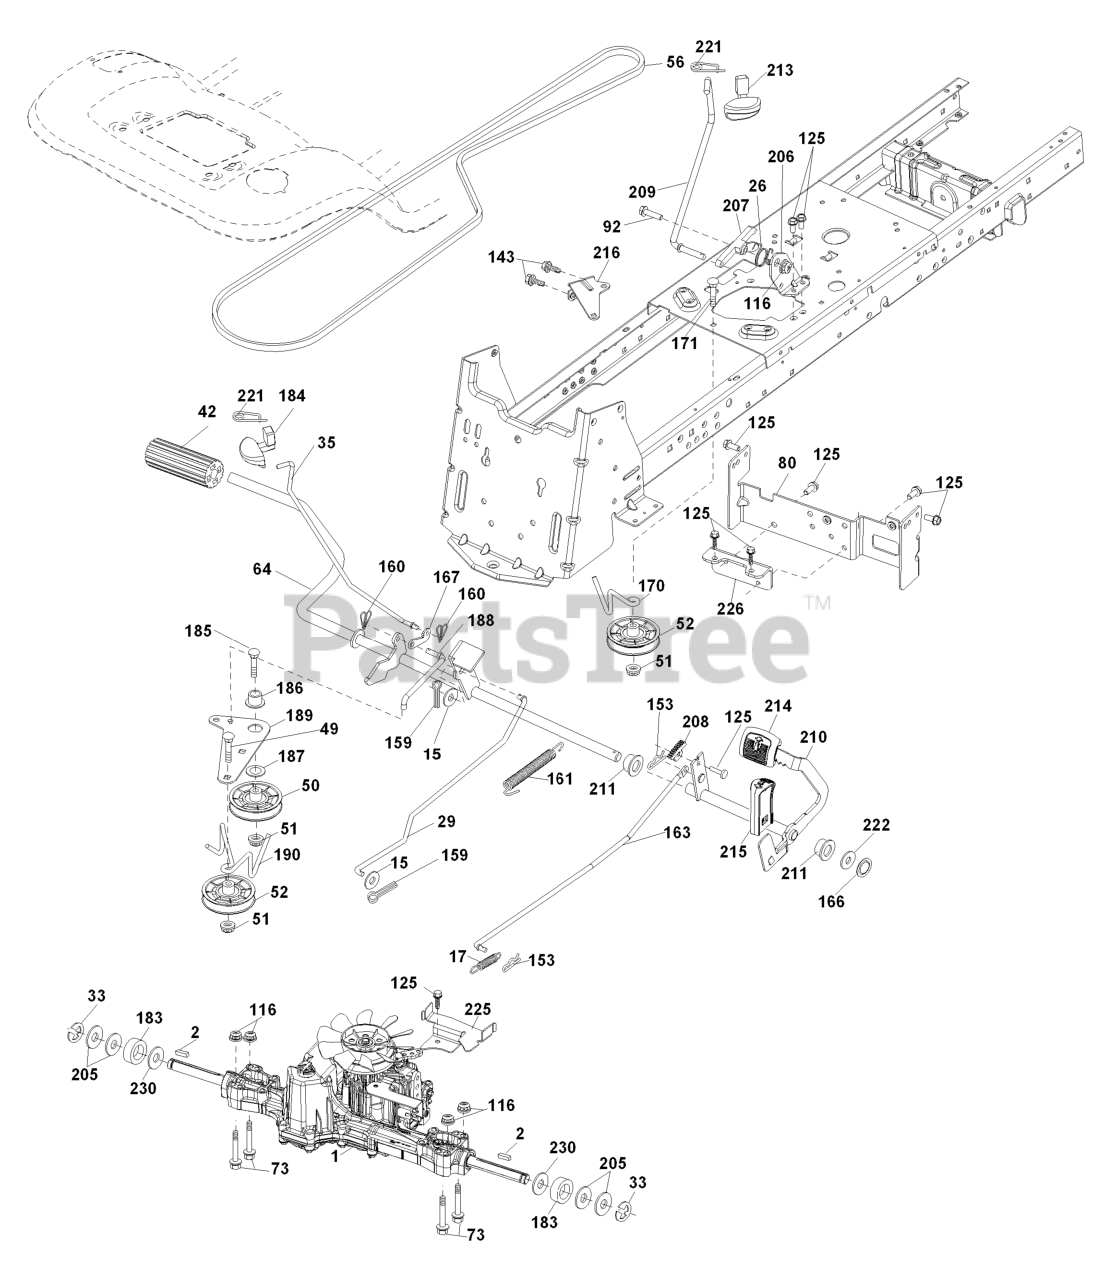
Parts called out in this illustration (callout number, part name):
1	TRANSAXLE, TUFFTORQ K46
2	SQUARE KEY
15	WASHER
17	SPRING.BRAKE.K46
26	SPRING.RETURN.CRUISE
29	ROD.BRAKE.K46
35	ROD.BRAKE.PARKING.GT.H
42	PEDAL COVER T
50	IDLER.FLAT.910.OFFSET
51	NUT LOCK FLG 3/8-16 UNC
52	IDLER.V-GROOVE.910.OFFSET
56	V-BELT.MOWER.92.40.42/K46
64	SHAFT.ASM.PEDAL.BRK.CNTR
80	STRAP TORQUE
92	BOLT
116	NUT LOCK HEX FLANGE 5/16-18
125	SCREW
143	Screw 5/16-18 x 1/2
153	RETAINER M
159	COTTER PIN
160	RETAINER CLIP
161	SPRING.RETURN.CLUTCH.2006
163	ROD.CONTROL.PEDAL.K46
166	NUT.PUSH.625.2006
167	LATCH.BRAKE.SPRING
170	KEEPER.V-IDLER.CENTER.
171	BOLT
183	SPACER AXLE
184	HANDLE.PARKG.BRK.HUSQ X667
185	BOLT
186	SPACER.RETAINER
187	WASHER 12/32X2X10GA
188	RP.LINK.CLUTCH.GROUND.DRIVE
189	BELLCRANK.GROUND.DRIVE.TEX.
190	KEEPER.BELLCRANK.DRIVE
206	BRKT.MOUNT.LATCH.CRUIS
207	LATCH.CONTROL.CRUISE
208	GEAR.SECTOR.CONTROL.CR
209	ROD.CONTROL.CRUISE.GT.
210	ROCKER.ASM.PEDAL.CONTR
211	BEARING.NYLON
213	KNOB.CONTROL.CRUSIE.HU
214	PEDAL.FORWARD.TEX.GT.4
215	PEDAL.REVERSE.TEX.GT.4
216	BRACKET.PULLEY.IDLER.W/TEX
221	RETAINER.SPRING.CLIP.H
222	WASHER 21/32 X 1-1/4 X 10 GA.
225	KEEPER.BELT.TRANSAXLE.K46
226	BRACKET.MOUNT.TORQUE.K46.TLT
230	WASHER.HARDENED
